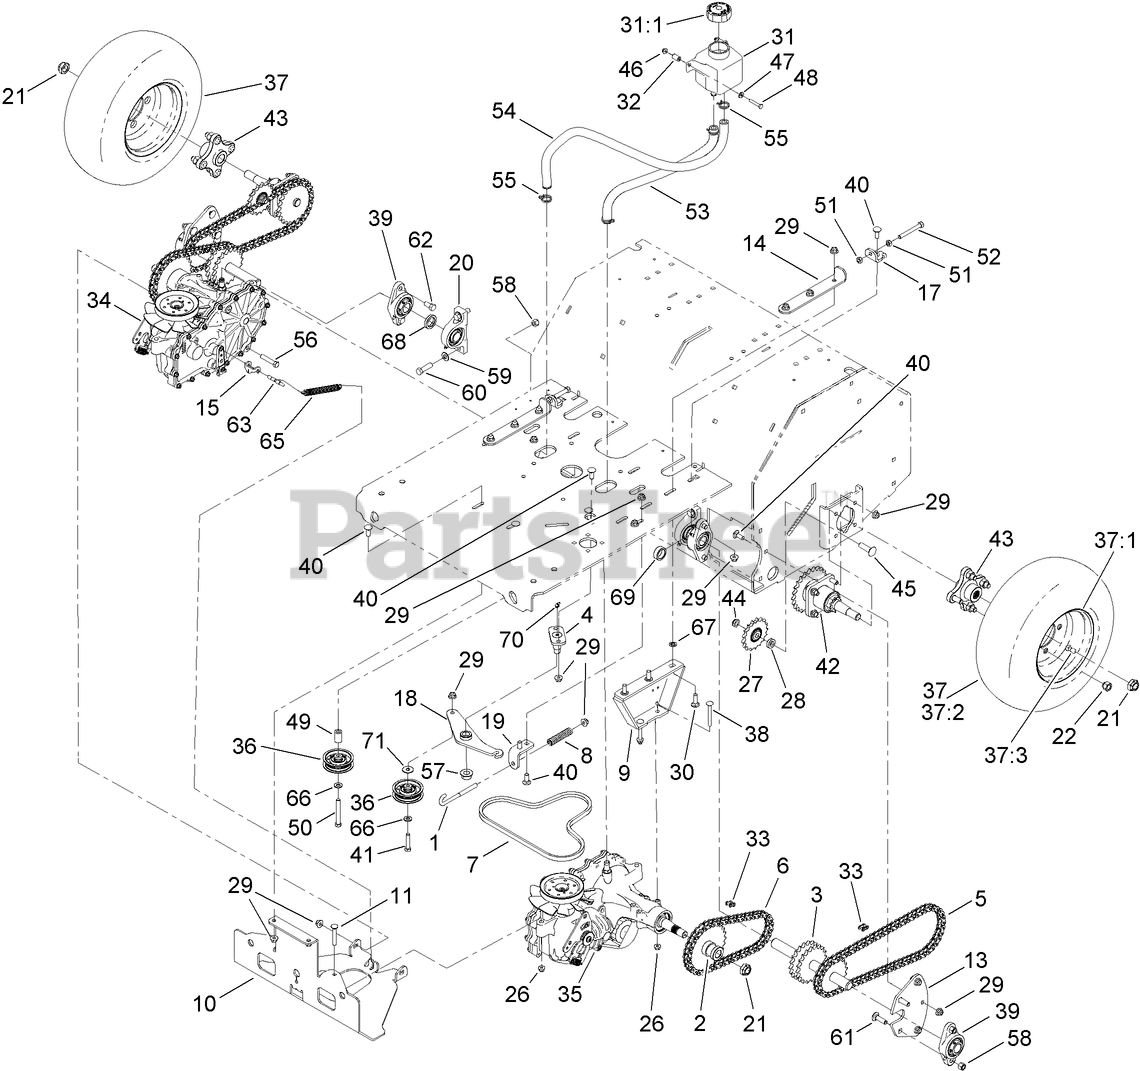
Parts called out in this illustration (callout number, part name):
1	HOOK-J
2	HUB-CHAIN DRIVE
3	JACKSHAFT
4	PIVOT-IDLER
5	CHAIN-ROLLER, #50, 65 LINKS
6	CHAIN-ROLLER #50, 47 PITCHES
7	BELT-BLOWER
8	SPRING-COMPRESSION
9	MOUNT-TRANSMISSION
10	GUARD-TRANSMISSION
11	BOLT-CARR
13	PLATE-JACKSHAFT
14	PLATE-ADJUSTMENT, TRANSMISSION
15	YOKE-BRAKE, PARK
17	BRACKET-HYDRO, ADJUST
18	IDLER ARM ASM
19	BRACKET-IDLER SPRING
20	BEARING-PILLOW BLOCK
21	NUT-LOCK
22	NUT-LUG
26	NUT-HF, NI
27	SPROCKET-IDLER, 17T
28	WASHER
29	NUT-HF, NI
30	BOLT-CARR
31	TANK-HYD
31:1	CAP-RESERVOIR, HYD
32	SPACER
33	LINK-CONNECTING
34	RH TRANSMISSION ASM
35	LH TRANSMISSION ASM
36	PULLEY-IDLER, FLAT
37	TIRE ASM (16 X 6.50-8)
37:1	RIM (8 x 5.375)
37:3	STEM-VALVE
38	SCREW-CARR
39	BEARING-FLANGE, 2 BOLT
40	BOLT-CARR
41	SCREW-HH
42	AXLE AND BEARING ASM
43	HUB-OFFSET
44	NUT-LOCK, NI
45	SCREW-CARR
46	NUT-HF
47	WASHER-FLAT
48	SCREW-HH
49	SPACER-IDLER
50	SCREW-HH
51	NUT-HEX
52	SCREW-HH
53	HOSE-HYDRAULIC
54	HOSE-HYDRAULIC
55	CLAMP-HOSE
56	SCREW-HH
57	NUT-FLANGE, CENTERLOCK
58	NUT-LOCK, NI
59	WASHER-FLAT
60	SCREW-HH
61	BOLT-CARR
62	SCREW-HH
63	PIN-BRAKE, PARK
65	SPRING-DOOR
66	WASHER-FLAT
67	NUT-PUSH
68	SPACER
69	SPACER
70	FITTING-GREASE
71	WASHER
